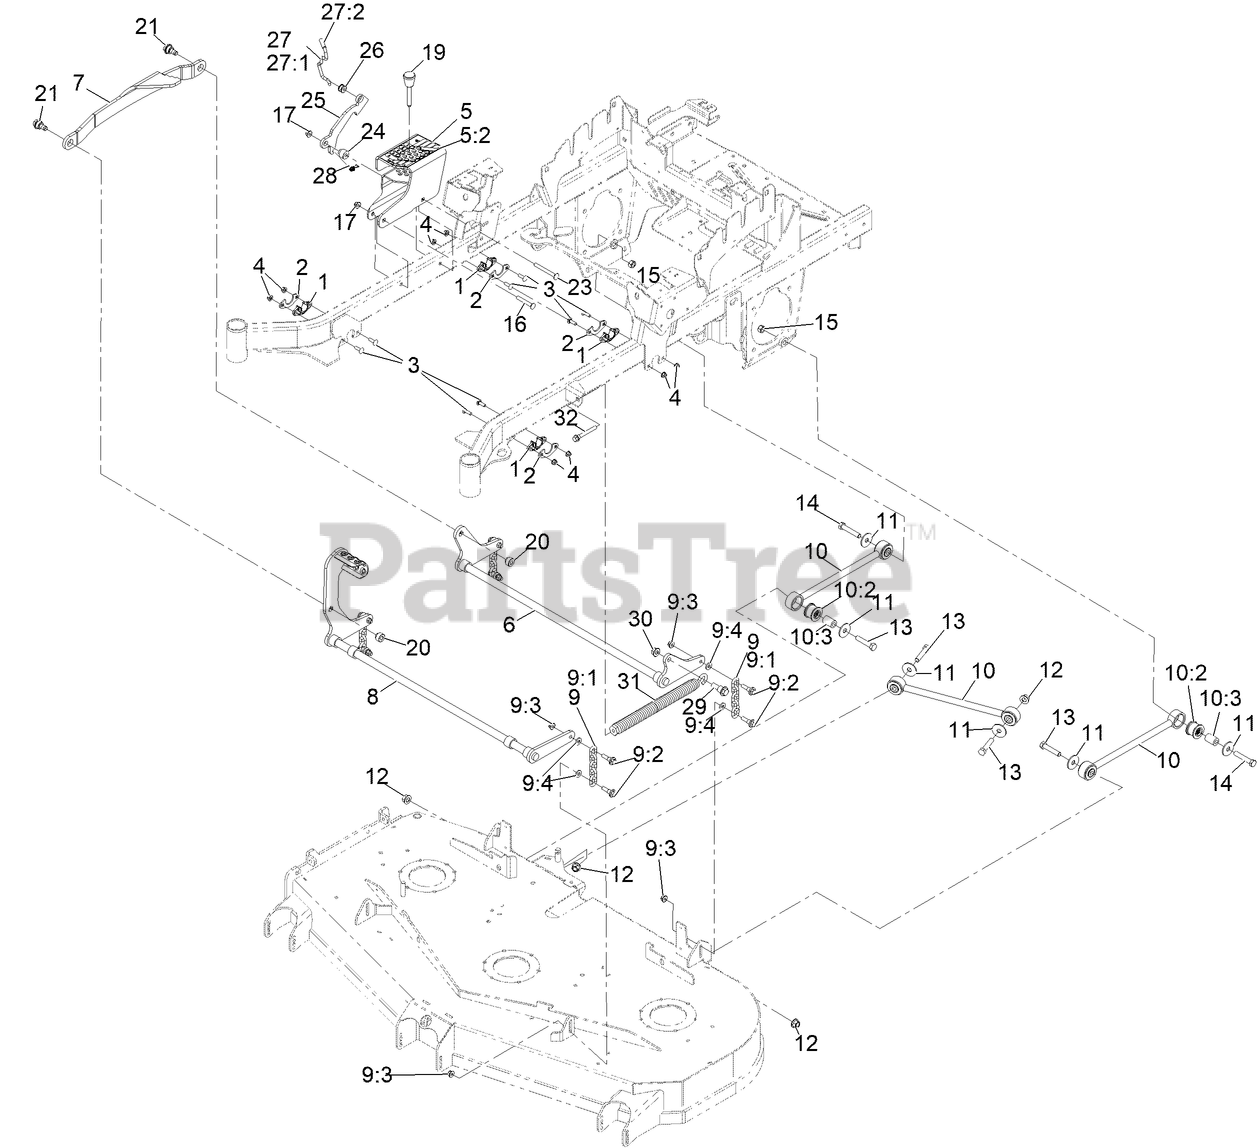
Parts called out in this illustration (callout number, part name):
1	BEARING-FLANGE
2	PLATE, HOC BACKER
3	SCREW-CARR
4	NUT-HF, NI
5	ASM, HOC Index W/ Decal
5:2	Decal-Height Of Cut
6	Weld, Rear Cross Shaft
7	Strap, Lift
8	Weld, Front Cross Shaft
9	DECK CHAIN ASM
9:1	CHAIN-LIFT, DECK
9:2	BOLT-SHOULDER
9:3	NUT-HF, NI
10	DECK STRUT ASM
10:2	BUSHING-SUSPENSION, RUBBER
11	WASHER-THRUST
12	Nut-Lock 1/2-13
13	SCREW-HH
14	SCREW-HH
15	NUT-HEX
16	SCREW-CARR
17	NUT-HF, NI
19	PIN-HOC
20	Spacer, HOC
21	BOLT, SHOULDER
23	SCREW-CARR
24	SPACER-STEPPED
25	LATCH, TRANSPORT
26	GROMMET
27	Release, Transport
27:1	Link, Transport Latch
27:2	GRIP-LEVER
28	SPRING, EXTENSION
29	SCREW-SHOULDER HHF
30	NUT-HF, NI
31	SPRING-EXTENSION
32	BOLT-SHOULDER
